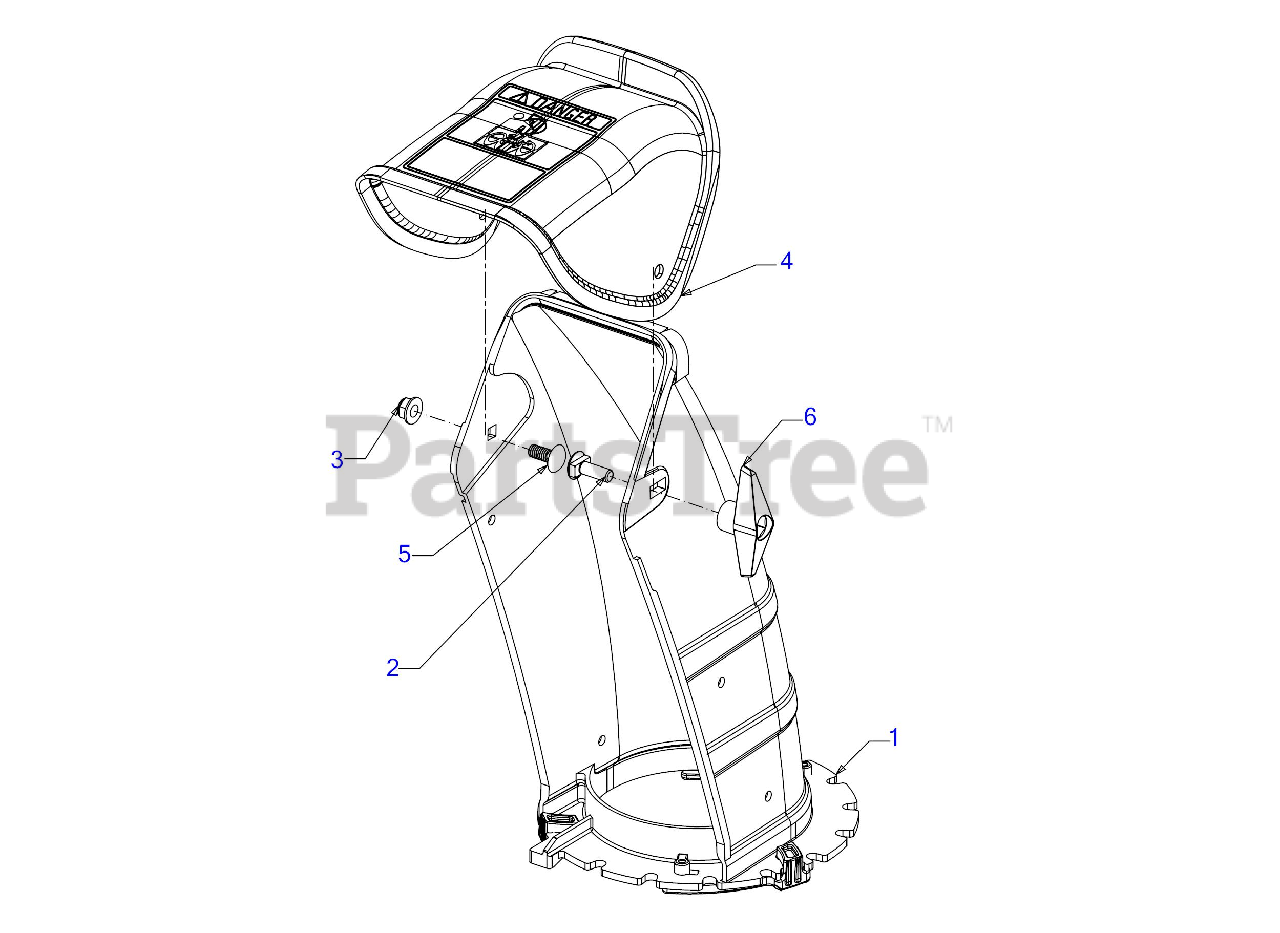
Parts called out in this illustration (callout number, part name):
1	2-WAY LOWER CHUTE ASSEMBLY
2	CARRIAGE BOLT 5/16-18 x 1
3	FLANGE LOCK NUT 5/16-18
4	UPPER CHUTE
5	CARRIAGE BOLT 5/16-18 x .75
6	KNOB ASSEMBLY-W/NUT
